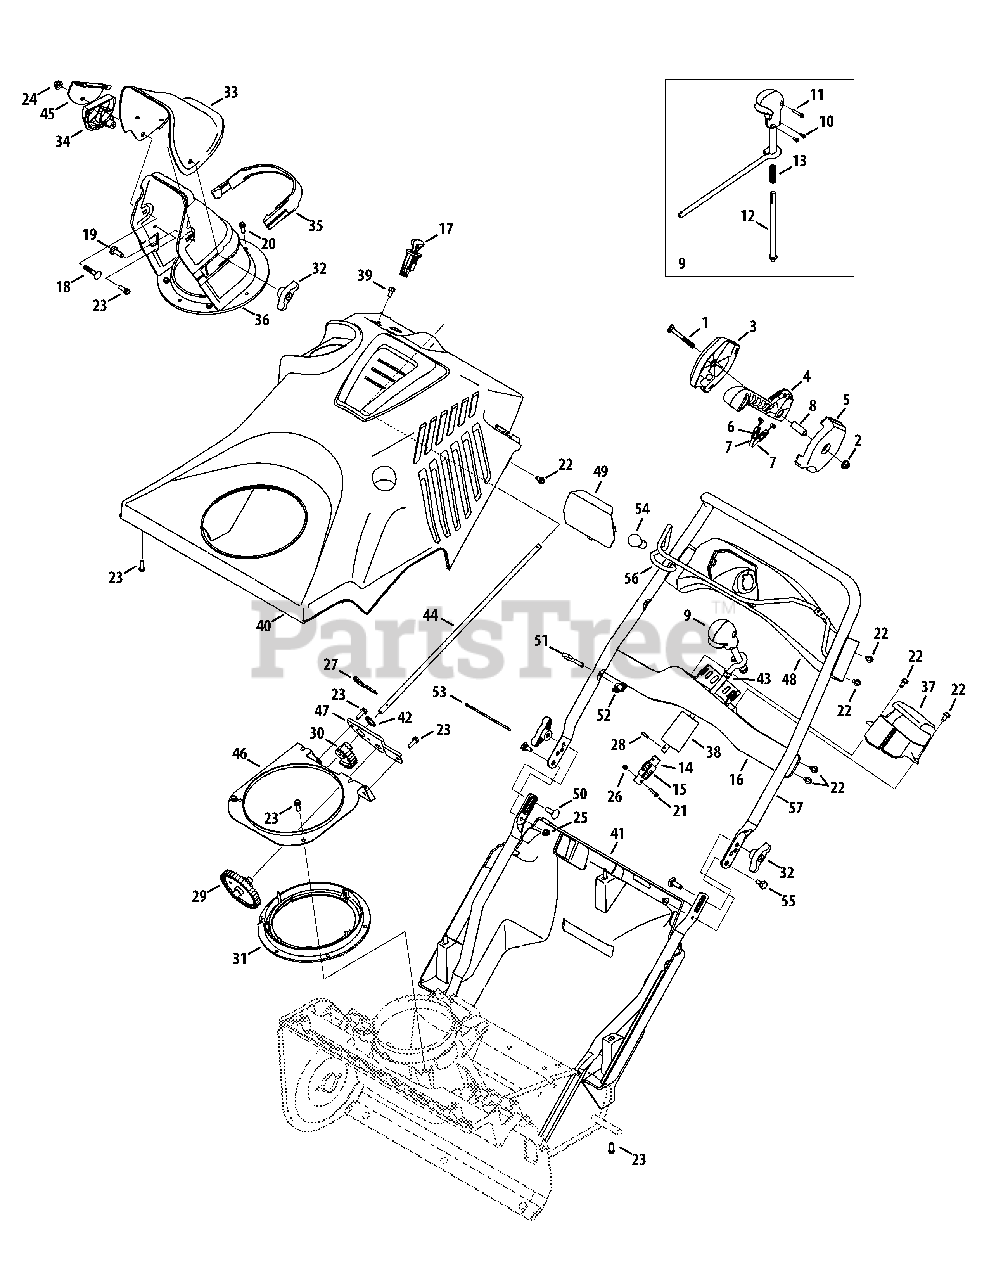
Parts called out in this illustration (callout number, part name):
1	Carriage Bolt, 5/16-18 x 2.5
2	Flange Lock Nut, 5/16-18
3	Chute Control Panel
4	Cable Handle Guide
5	Chute Control Panel, Inner
6	Cable Clip
8	Spacer, .325 ID x .496 OD x 1.34
9	Chute Control Assembly
10	Screw, #6 x .375
11	Screw, #8 x 1.00
13	Spring, .460 OD x 1.469
14	Joint Block Assembly
15	Roll Pin, 3/16 Dia. x 1.1 LG.
17	Ignition Switch Assembly
18	Carriage Bolt, 5/16-18 x 1.00
19	Carriage Bolt, 5/16-18 x .75
20	Hex Washer Screw, 1/4 x .750
21	Screw, #8-32 x .875
22	Hex Washer Screw, 1/4-20 x .500
23	Screw, Hi-Lo:1/4-15, 0.75
24	Flange Lock Nut, 5/16-18
25	Flange Lock Nut, 1/4-20
26	Hex Lock Nut, #8-32
27	Cotter Pin
28	Pin, .156 x .875
29	Bevel Gear, 40T/11T
30	Spur Gear, 35T
31	Bevel Gear, 95T
32	Wing Knob, 5/16-18
33	Upper Chute
34	Cable Guide
35	Chute Plug
36	Lower Chute
37	Chute Cover
38	Grip, 1.18 x 3.33
39	Hex Washer Screw, 1/4-15 x .50
40	Top Cover
41	Bottom Cover
42	Flat Washer, .75 x 1.00 x .06
43	Plastic Bushing, .380 ID
46	Gear Retainer Bracket
47	Gear Mounting Plate
48	Handle Panel Assembly
49	Handle Panel Lens
50	Carriage Screw, 5/16-18 x 1.00
51	Eye Bolt, 1/4-20
52	Handle Knob, 1/4-20
53	Cable Tie
55	Shoulder Screw, .375 x .148 x 1/4-20
